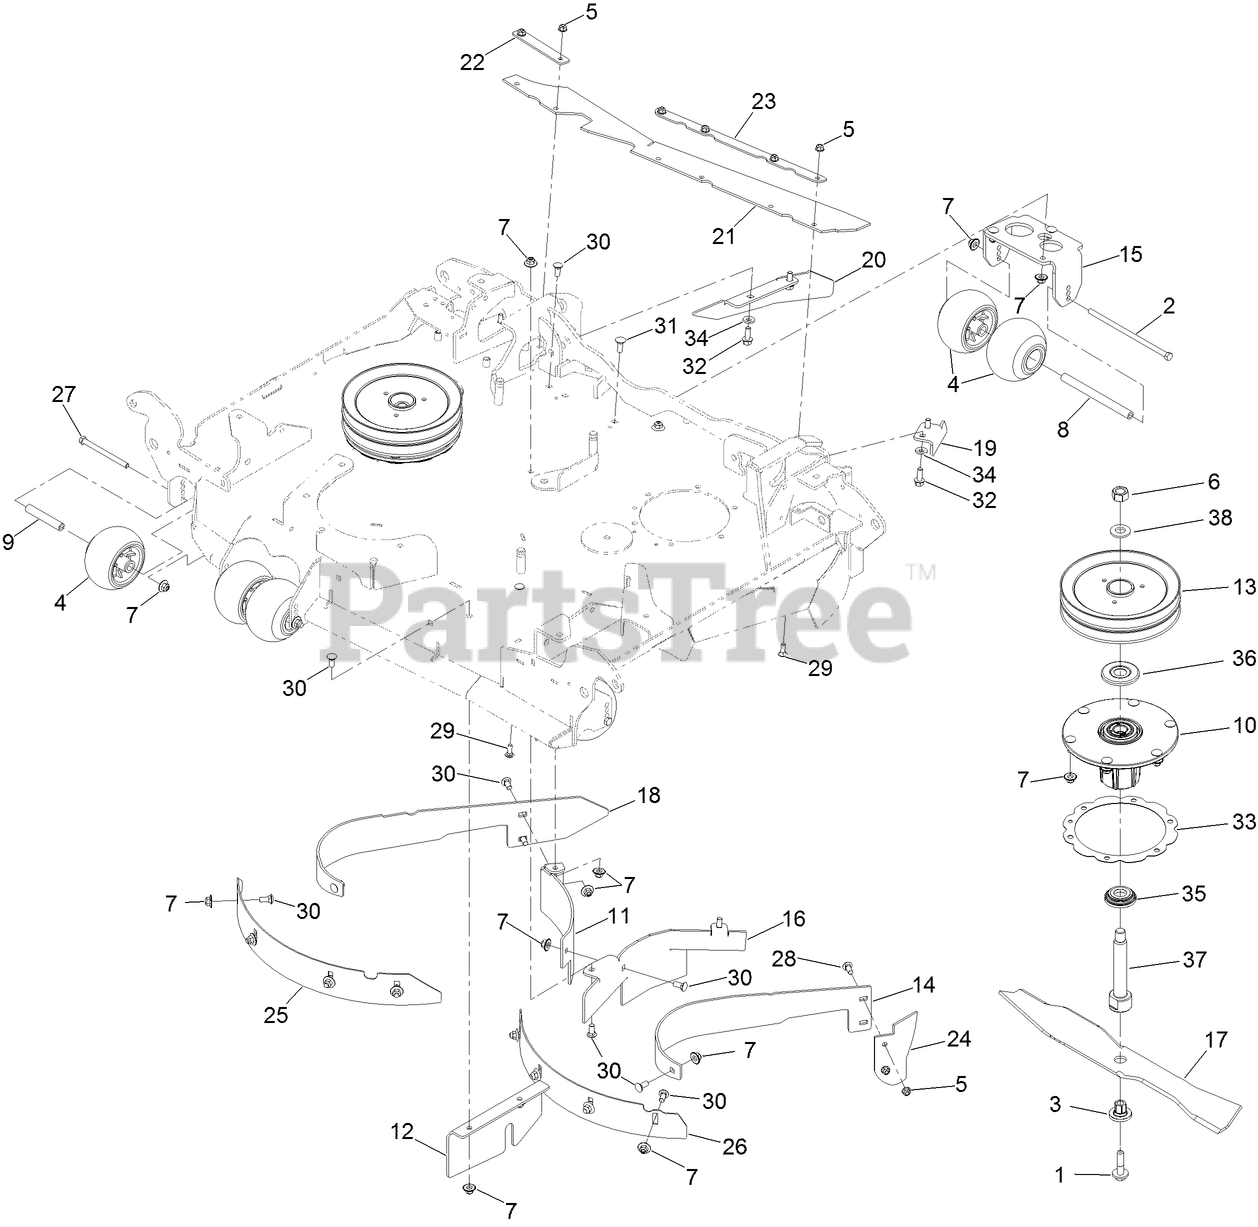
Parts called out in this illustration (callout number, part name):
1	SCREW-SEMS
2	SCREW-HH
3	BUSHING-HEX
4	ROLLER-SCALP, ANTI
5	NUT-HF, NI
6	NUT-HEX
7	NUT-FLANGE, NI
8	SPACER-WHEEL
9	SPACER-WHEEL SHORT
10	SPINDLE ASM
11	BAFFLE-CENTER, REAR (RH)
12	PLATE-BLOCK, FRONT
13	SHEAVE-DOUBLE BLADE DRIVE
14	BAFFLE-DOGLEG, CENTER (LH)
15	BRACKET-ANTISCALP, REAR
16	BAFFLE-CENTER
17	BLADE-24.50 MULCH
18	BAFFLE-DOGLEG, CENTER (RH)
19	BAFFLE-BREAKER
20	PLATE-FIN, DISCHARGE
21	FLAP-DISCHARGE
22	SUPPORT-FLAP, LH
23	SUPPORT-FLAP, LH
24	GUARD-DISCHARGE
25	BAFFLE-DEPTH, LH
26	BAFFLE-DEPTH, RH
27	SCREW-HH
28	SCREW-CARR
29	SCREW-CARR
30	BOLT-CARR
31	BOLT-CARR
32	SCREW-HHF
33	RING-SPACER, HOUSING
34	WASHER-BELLEVILLE
35	GUARD-BOTTOM
36	GUARD-BEARING, TOP
37	SHAFT-SPINDLE
38	WASHER
